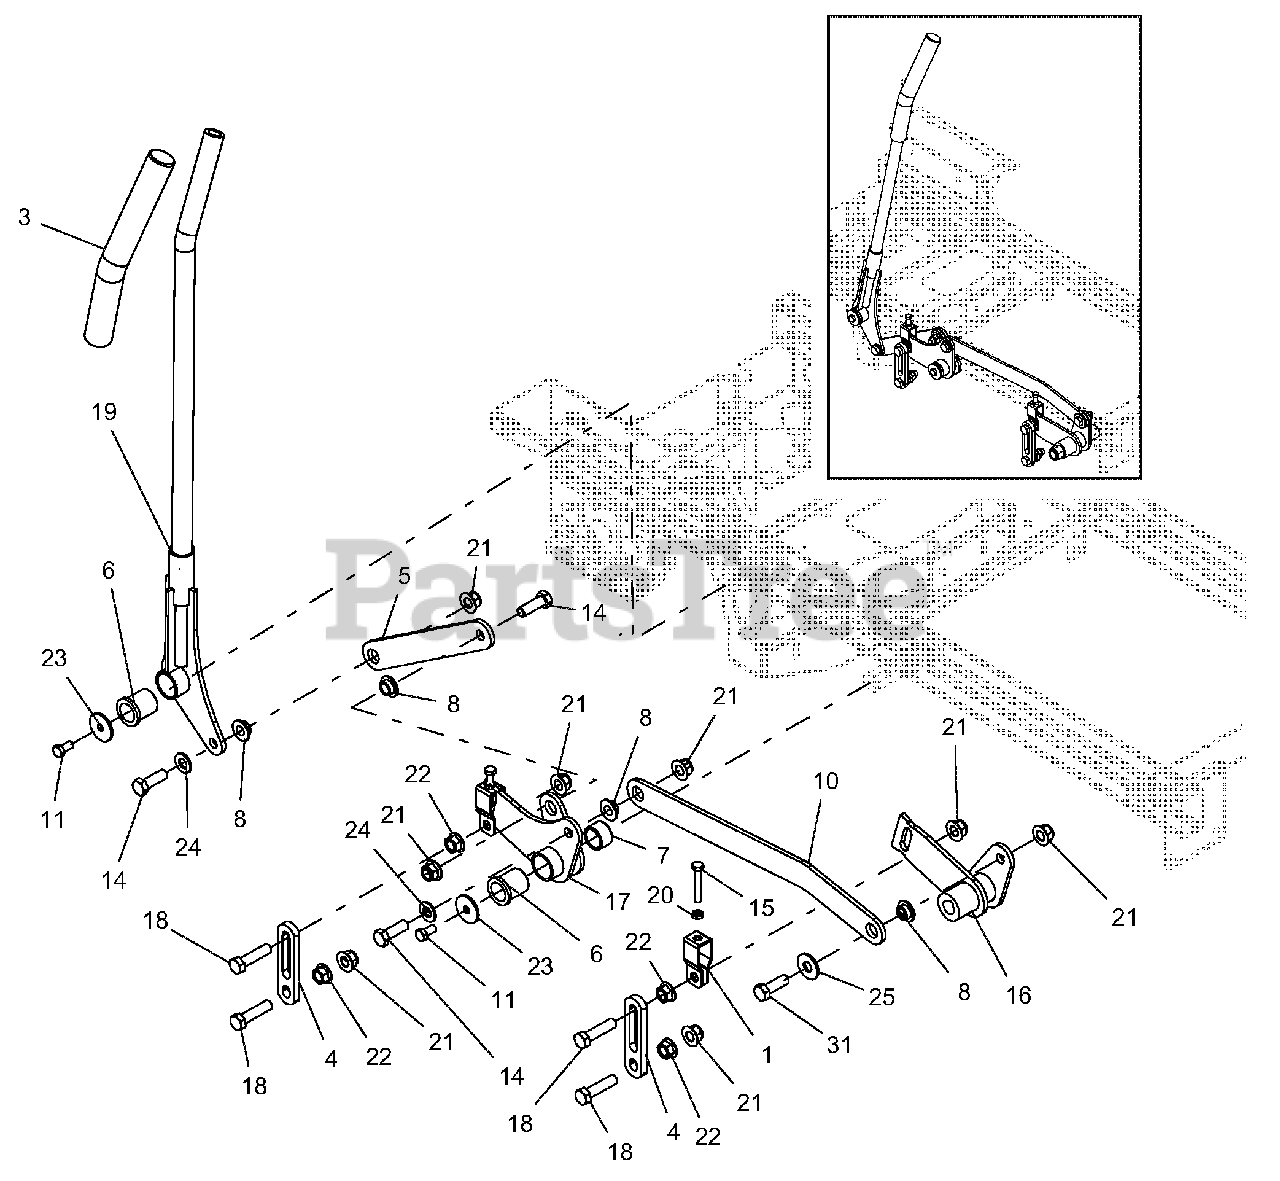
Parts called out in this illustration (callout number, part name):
1	BRKT, DECK LEVELING
3	GRIP, HANDLEBAR
4	LINK, DECK LIFT - SHORT
5	LINK, DECK LIFT HANDLE
6	BSHG-FLG 1.00X1.25X1.5X1.5
7	BSHG, 1.00 X 1.25 X .75
8	BSHG, FLANGE .515X.750X.420X1.12
10	PLATE, DECK ARM
11	BLT-HEX .38-16X.75 GR5 YWZC
14	BLT-HEX .50-13X1.50 GR5 YWZC
15	BLT-HEX .31-18X2.00 FTH GR5 YWZC
16	WLDMT, RH FRONT DECK ARM (BLACK)
17	WLDMT, REAR DECK ARM
18	BLT-HEX .50-13X2.00 GR5 YWZC
19	WLDMT, DECK LIFT HANDLE
20	NUT, JAM .312-18 YWZC
21	NUT-LK-NYL-FLG .50-13 YWZC
22	NUT .50-13 WIZ FLANGE
23	WSHR-FL-STL .380X1.50X.125 YWZC
24	WSHR-FL-STL.531X1.06X.095YWZC
25	WSHR-FL-STL.563X1.38X.109YWZC
31	BLT-HEX .50-13X1.50 GR5 YWZC
